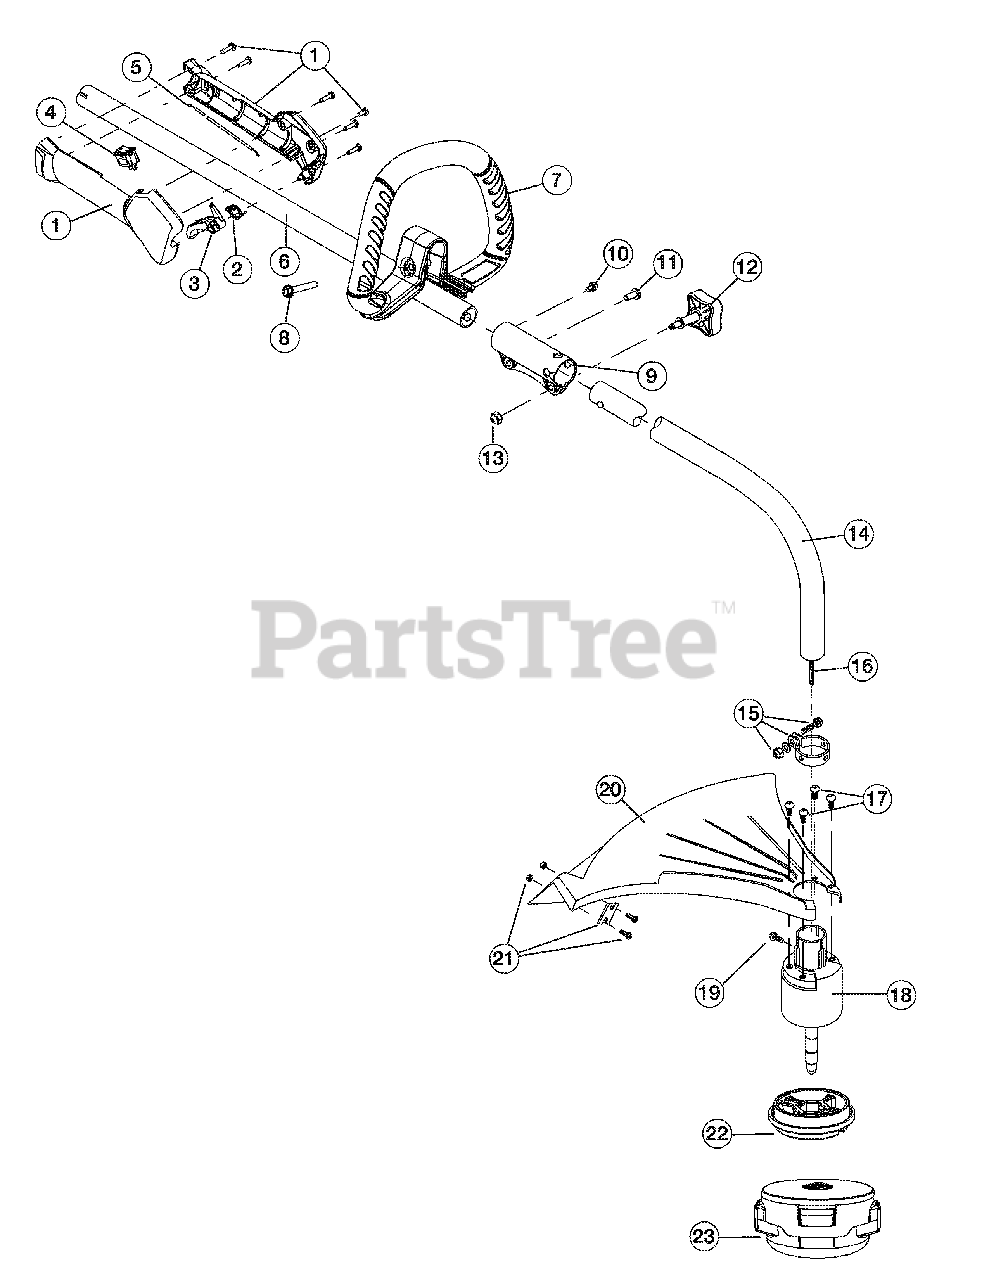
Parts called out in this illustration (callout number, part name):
1	Throttle Housing Assembly (Incl. Ref No. 2-4)
2	Throttle Trigger Spring
3	Throttle Trigger
5	Throttle Cable Assembly
6	Upper Drive Shaft Housing Assembly
7	D-Handle Assembly (Incl. Ref No. 8)
9	Split boom Coupler (Incl. Ref No. 10-13)
12	Adjustment Knob (Incl. Ref No. 13)
13	Knob Retaining Nut
14	Lower Drive Shaft Housing Assembly (Incl. Ref No. 16)
15	Lower Clamp Assembly (Incl. Ref No. 19)
16	Lower Flexible Drive Shaft
17	Shield Mounting Screw
18	Bushing Housing Assembly
19	Anti-Rotation Screw
20	Shield Assembly (Incl. Ref No. 21)
21	Blade Assembly
23	Spool Assembly
